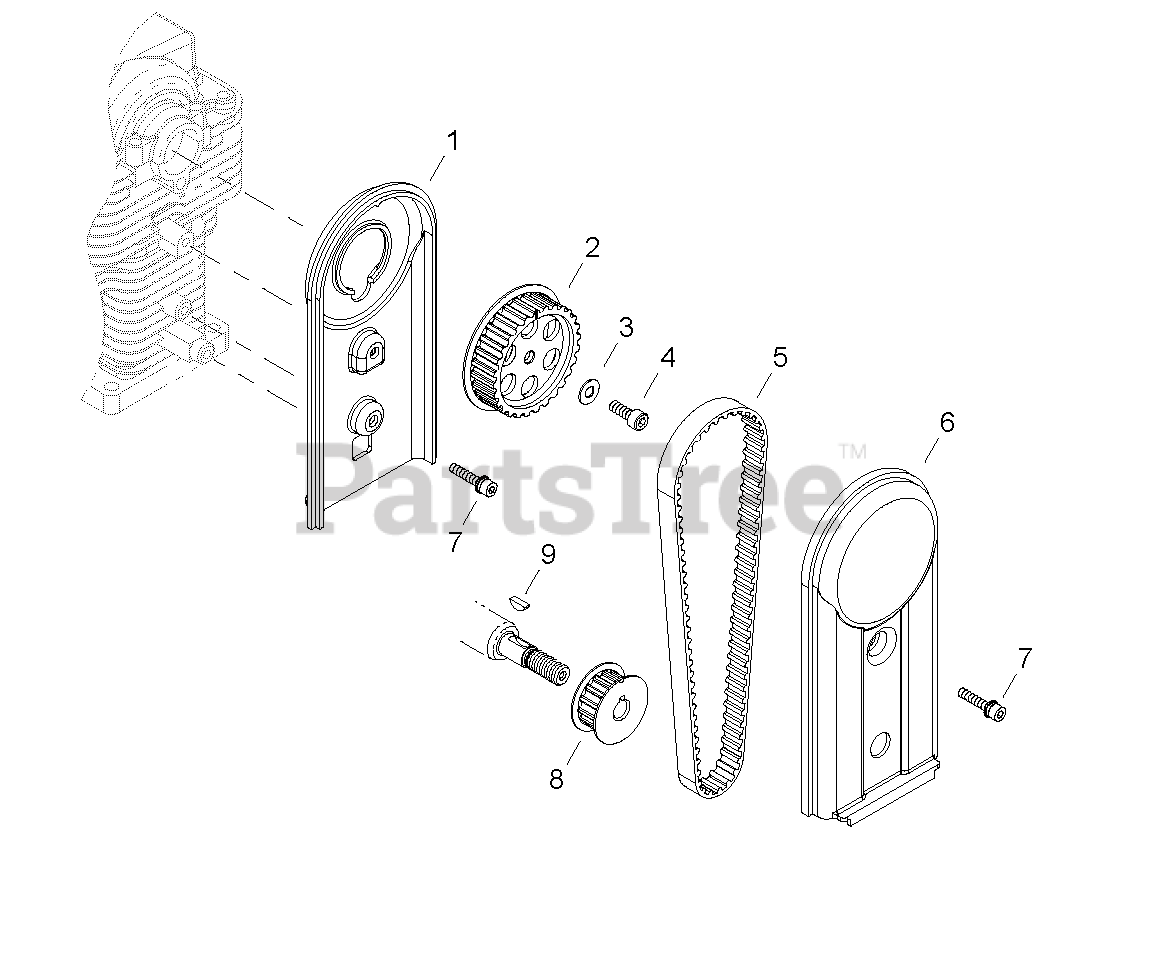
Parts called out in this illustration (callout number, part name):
1	CASE, BELT
2	PULLEY, CAM
3	WASHER 5.3×10×1
4	BOLT 5×14
5	BELT
6	COVER, BELT
7	BOLT M5×12
8	PULLEY, CRANK
9	KEY, WOODRUFF 3×10
